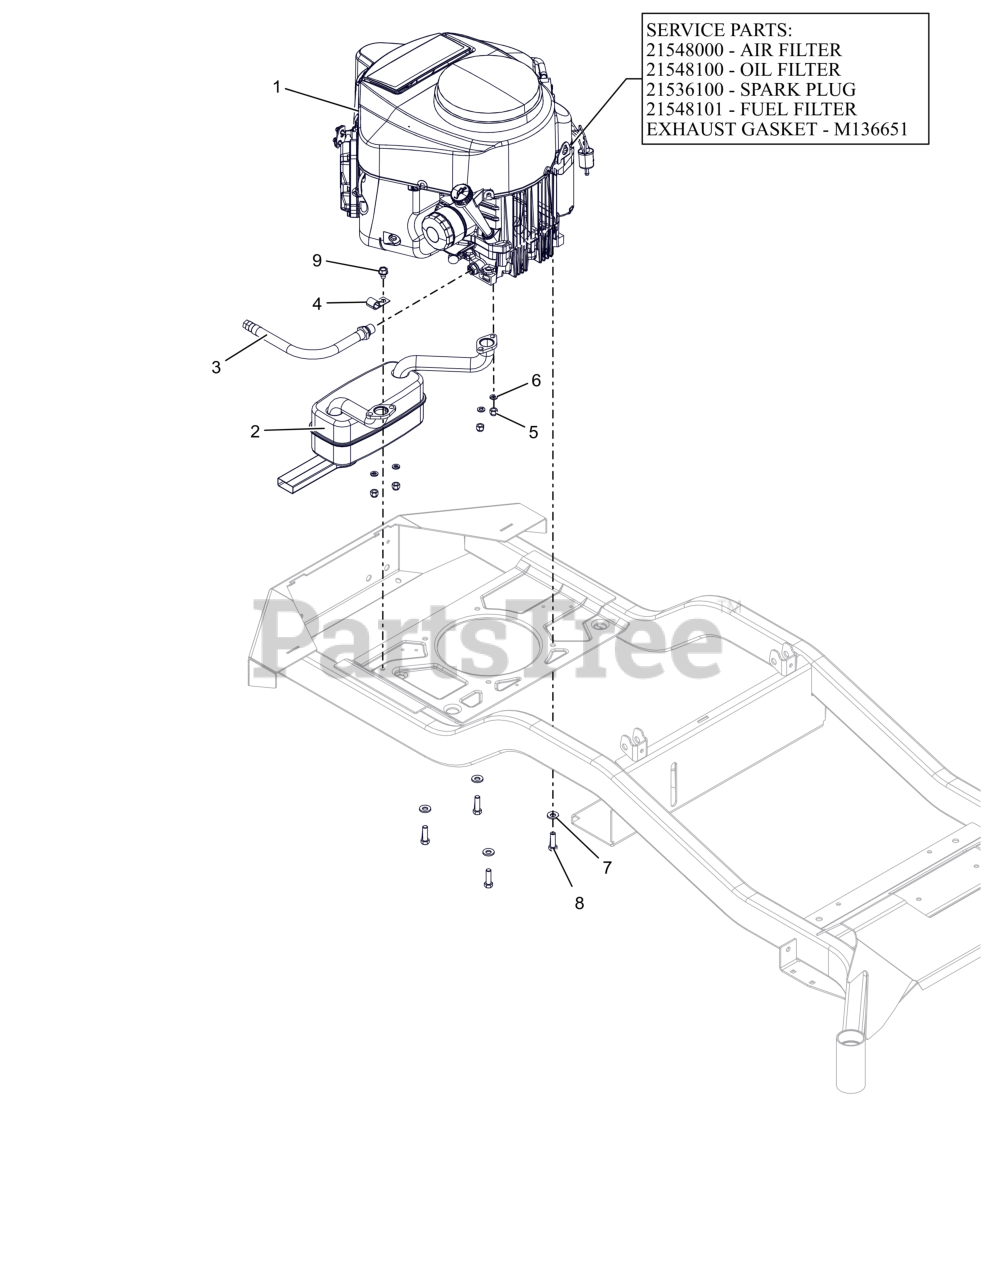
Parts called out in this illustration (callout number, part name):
1	ENGINE, KAWASAKI FR691 23HP
1	AIR FILTER, KAWASAKI FR
1	OIL FILTER, KAWASAKI FR
1	PLUG, SPARK
1	FUEL FILTER-KAWASAKI FR
1	GASKET, MUFFLER #
2	MUFFLER, KAWASAKI
3	HOSE, OIL DRAIN
4	J-CLAMP
5	NUT, LK-CTR-JAM M8-1.25 GR8.8 ZC120
6	WSHR,LK-REG .312X.078 ZCC
7	WASHER, 3/8" SPRING DISC
8	BLT, HEX .38-16X1.25 G5 ZCC NT
9	SCR,TAP .375-16X.50 HWH TR ZCC
